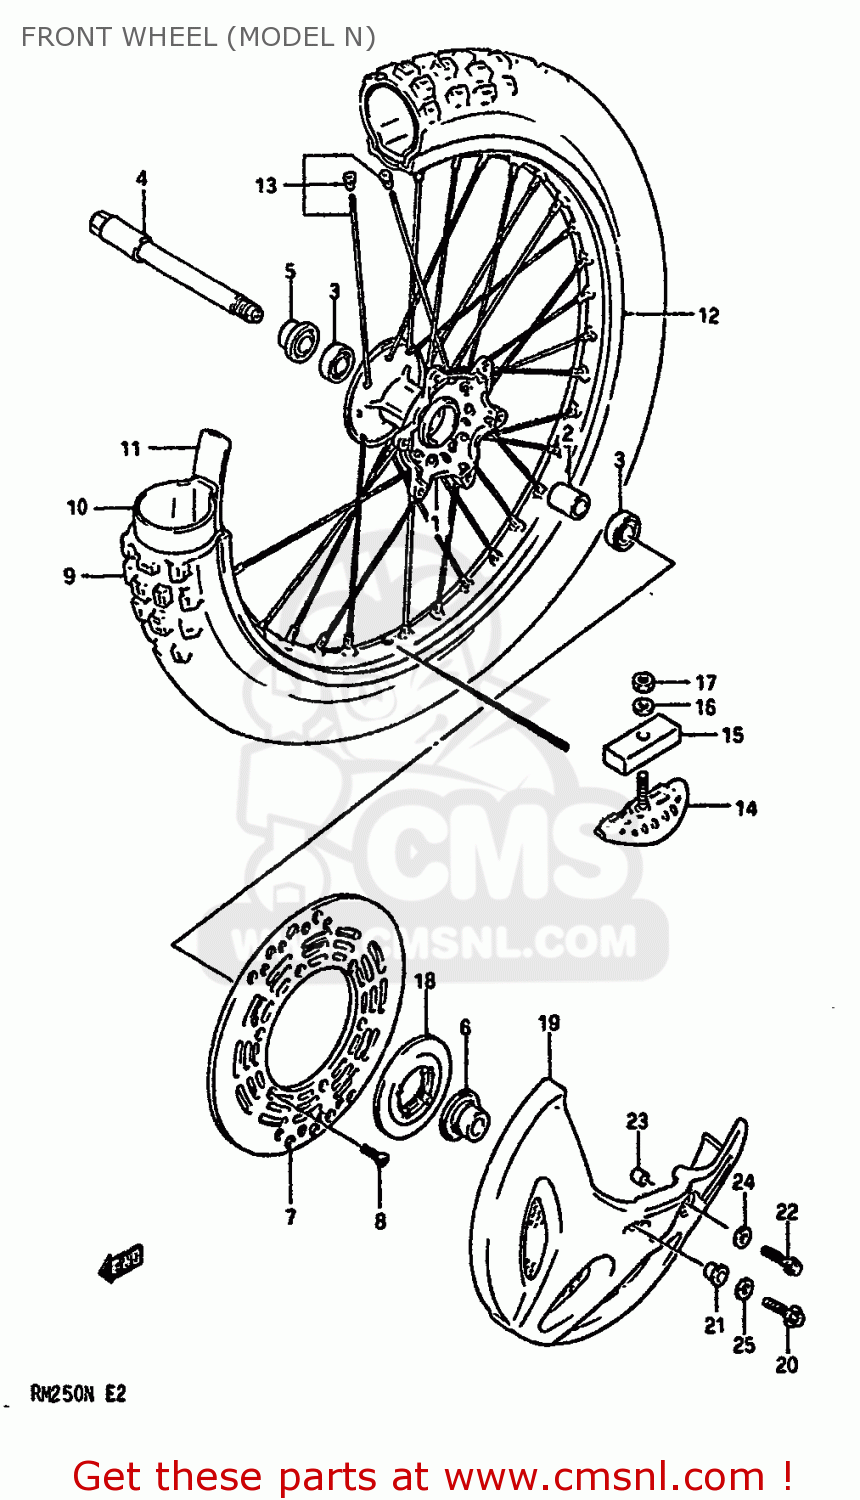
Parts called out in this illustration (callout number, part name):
1	HUB,FRONT
2	SPACER,FRONT HUB
3	BEARING
4	AXLE,FR
5	SPACER,FR AXLE,R
6	SPACER,FRONT AXLE,LEFT
7	DISC,FR BRAKE
8	SCREW
9	TIRE,FRONT 80/100-21
10	TUBE
11	PROTECTOR,WHEEL INNER
12	RIM,FRONT WHEEL (1.60X2
13	SPOKE SET,FRONT
14	STOPPER,BEAD
15	CUSHION,BEAD STOPPER
16	WASHER
17	NUT
18	CAP,FR HUB,L
19	COVER,FR BRAKE DISC
20	BOLT
21	WASHER (8.5X16X1.6)
22	BOLT
23	SPACER(6.1X8X14.5)
24	WASHER(6.5X18X1)
25	WASHER(8.5X18X1)
